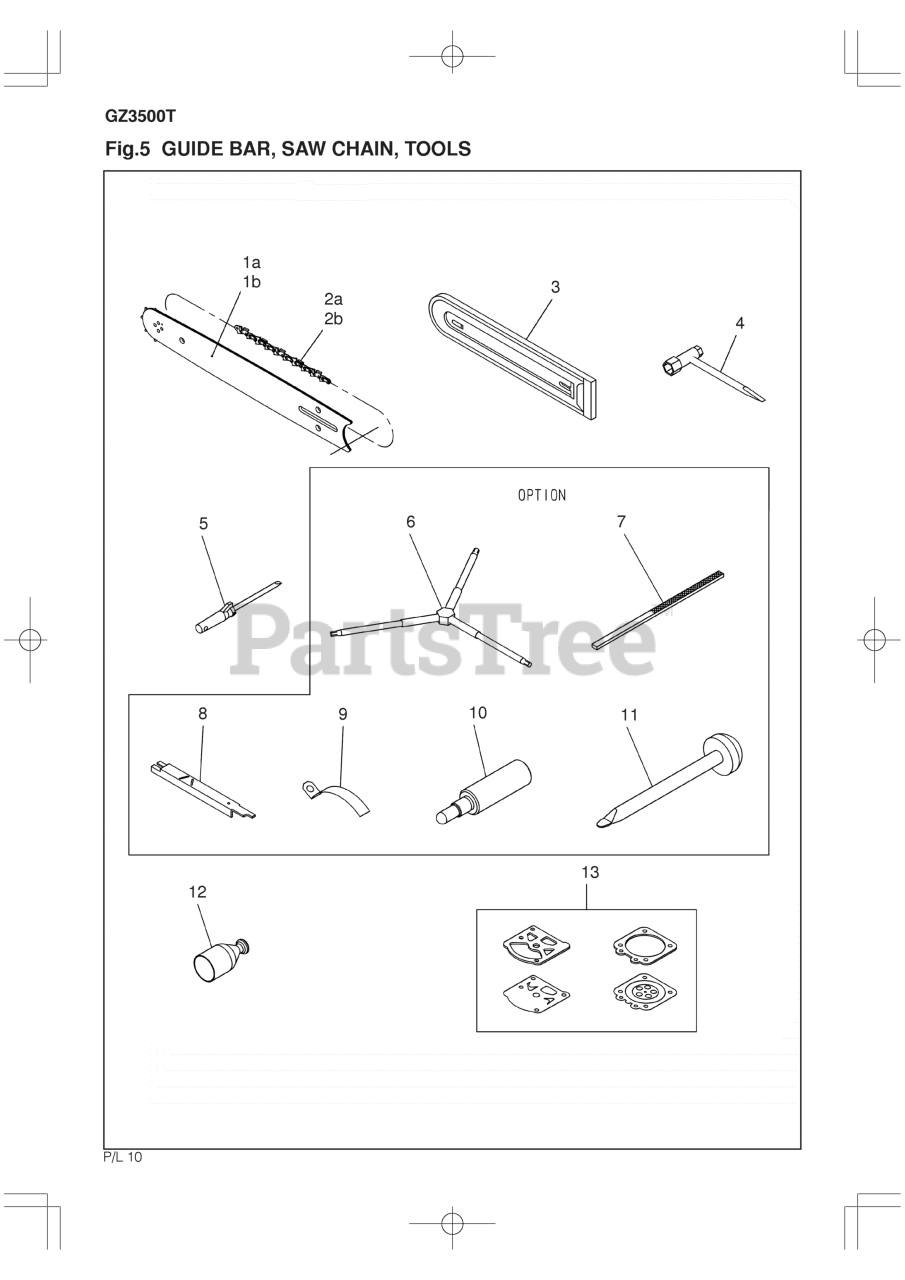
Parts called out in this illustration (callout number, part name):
3	PROTECTOR (14.5
6	HEXAGON WRENCH
9	GAUGE (TOOL)
10	STOPPER
11	GUIDE (TOOL)
12	GUIDE
13	GASKIT KIT
